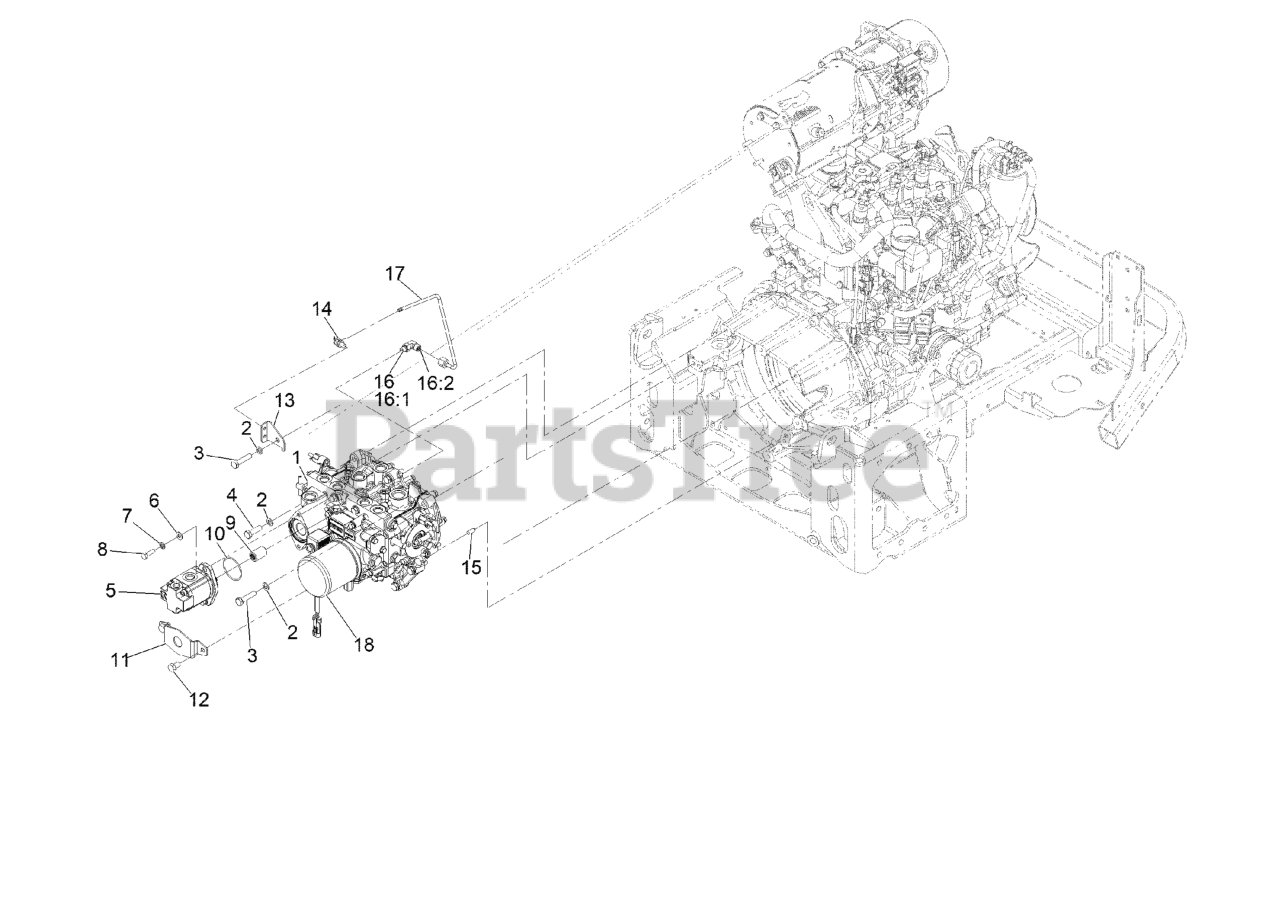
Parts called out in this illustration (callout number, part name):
1	TRANSMISSON ASM
2	WASHER-LOCK
3	SCREW-HH
4	SCREW-HH
5	HYD GEAR PUMP ASM
6	WASHER-PLAIN
7	WASHER-LOCK
8	SCREW-HH
9	COUPLER-SPLINE
11	SHIELD-SEAL
12	SCREW-HH
13	SUPPORT-TUBE
14	CLIP-TIE
15	PIN-DOWEL
16	FITTING-ELBOW, 90 DEG
16:1	O-RING
16:2	O-RING
17	TUBE ASM
18	FILTER-OIL, HYD
